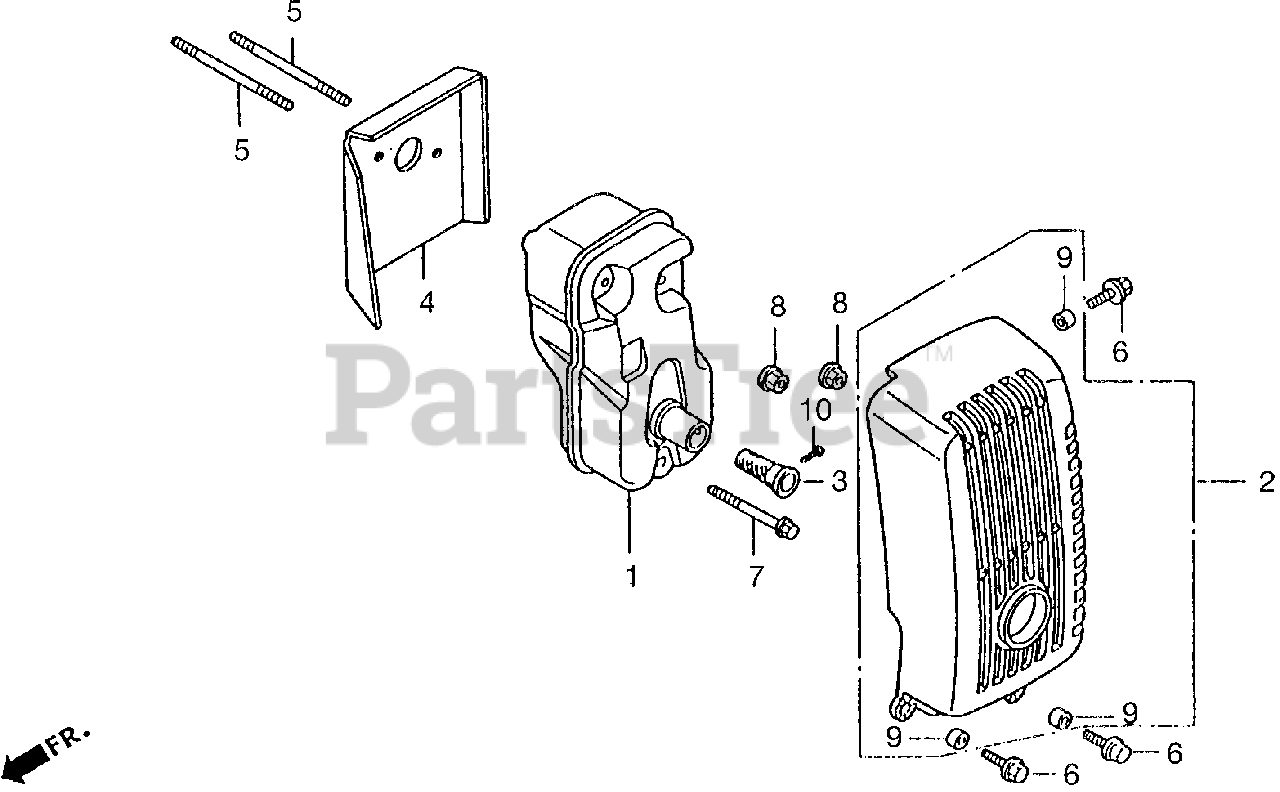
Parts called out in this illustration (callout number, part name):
1	MUFFLER
2	PROTECTOR, MUFFLER
3	ARRESTER, SPARK
4	GUIDE, AIR
5	BOLT 2, STUD (5X55)
6	BOLT, FLANGE (5X16)
7	BOLT, FLANGE (5X35)
8	NUT, SELF-LOCK (5MM)
9	COLLAR, TOP COVER
10	SCREW, TAPPING (4X8)
